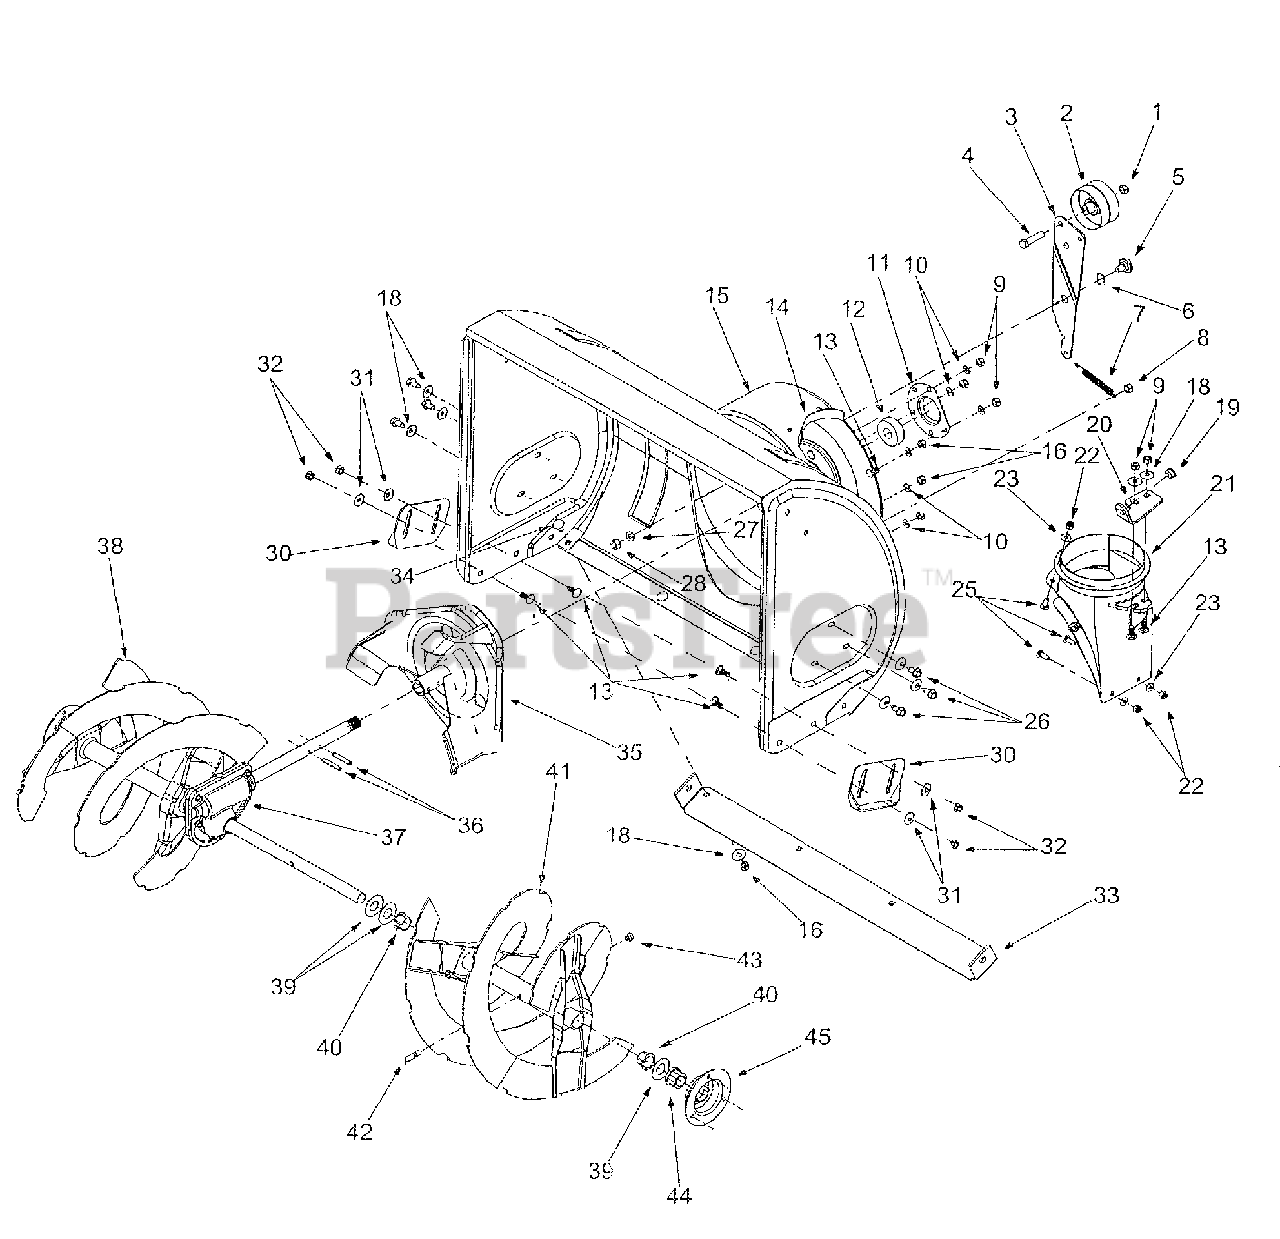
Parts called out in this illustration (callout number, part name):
1	Lock Jam Nut 3/8-24
2	Flat Idler
3	Auger Idler Arm
4	Hex Cap Screw 3/8-24 x 1.50
5	Shoulder Screw
6	Wave Washer
7	Extension Spring
8	Hex Nut 5/16-18
9	Hex Nut 5/16-18
10	Lock Washer 5/16
11	Housing
12	Ball Bearing
13	Carriage Bolt 5/16-18 x .75
18	Bell Washer
19	Bushing
20	Chute Crank Bracket
21	Chute Adapter
22	Hex Lock Nut 1/4-20
23	Flat Washer
25	Carriage Screw 1/4-20 x .75
26	Hex Washer Screw 5/16-18
27	Lock Washer 3/8
28	Hex Nut 3/8-16
31	Bell Washer
32	Hex Nut 5/16-18
33	24" Shave Plate
33	26" Shave Plate
33	28" Shave Plate
34	Carriage Bolt 5/16-18 x .62
35	Impeller Assembly
36	Pin
37	24" Gear Assembly
37	26" Gear Assembly
37	28" Gear Assembly
38	Spiral 28" RH
39	Flat Washer
40	Flange Bushing
41	Spiral 24" LH
41	Spiral 26" LH
41	Spiral 28" LH
42	Shear Bolt 5/16-18 x 1.5
43	Lock Nut 5/16-18
44	Hex Flange Bearing
45	Bearing Housing
